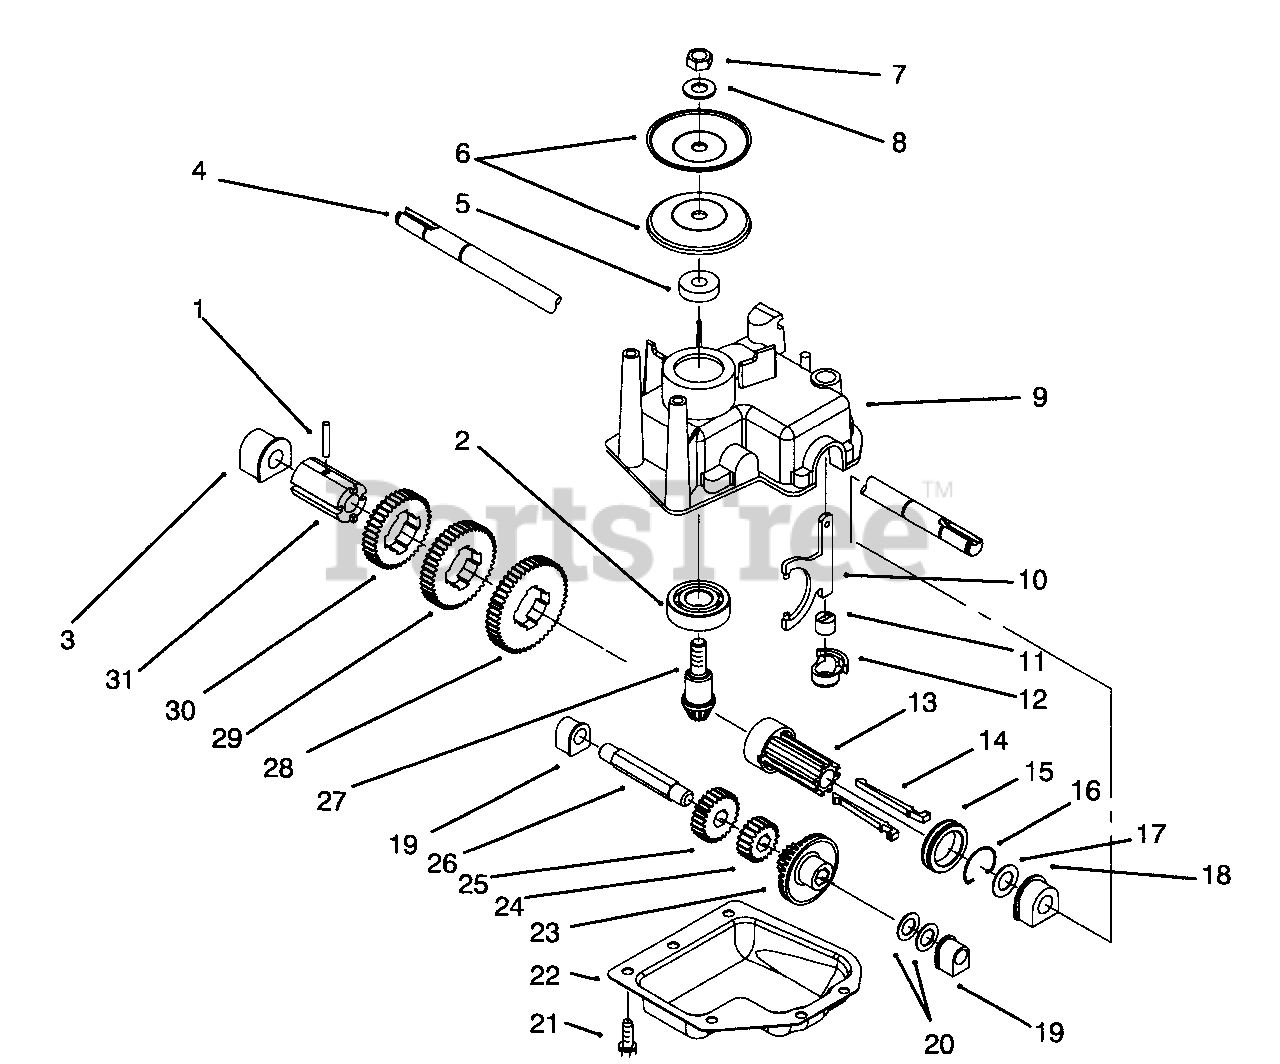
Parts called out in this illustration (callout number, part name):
2	Bearing-Ball
3	Bushing-Output
4	Shaft-Output
6	Pulley-Half
9	Gearcase-Upper
10	Yoke-Shift
11	Bushing-Yoke
12	Retainer-Shift Fork
13	Sleeve-Shift Key
14	Key-Shift
15	Collar-Shift
16	Clip-Spring
18	Bushing-Output
19	Bushing-Inter. Shaft
20	Washer-Thrust
22	Gear Case Cover
23	Pinion-15 Tooth
24	Pinion-20 Tooth
25	Pinion-25 Tooth
26	Shaft-Intermediate
27	Pinion-Bevel
28	Gear-49 Tooth
29	Gear-44 Tooth
30	Gear-39 Tooth
31	Sleeve-Gear
